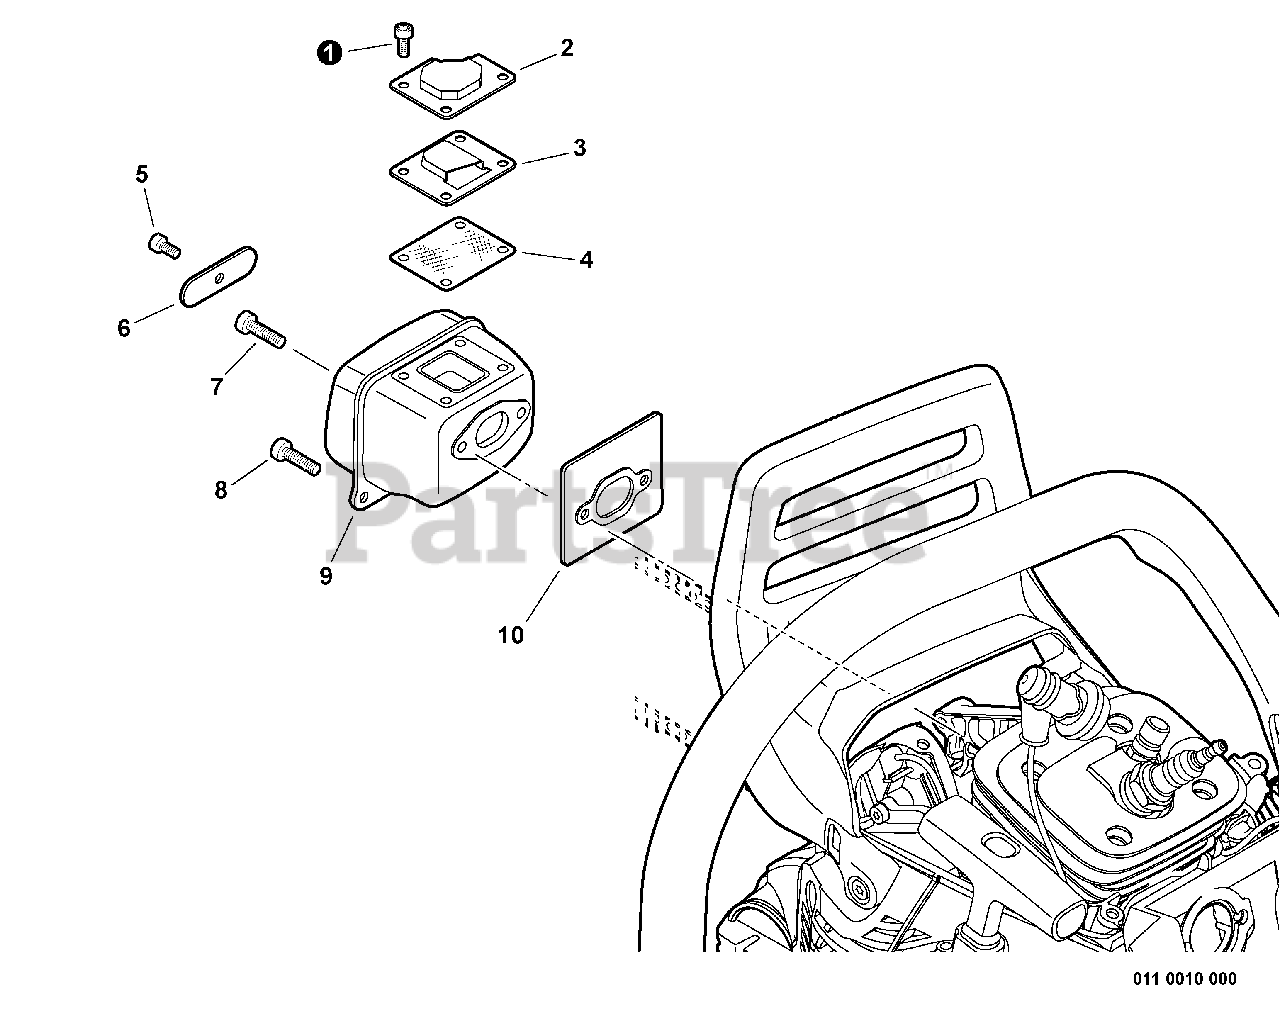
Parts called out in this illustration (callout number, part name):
1	BOLT, TORX 4×8
2	GUIDE, EXHAUST
3	GUIDE, EXHAUST
4	SCREEN, SPARK ARRESTER
5	BOLT, TORX 4×8
6	PLATE, MUFFLER
7	BOLT, TORX 5×20
8	BOLT, TORX 5×20
9	MUFFLER
10	GASKET, EXHAUST
